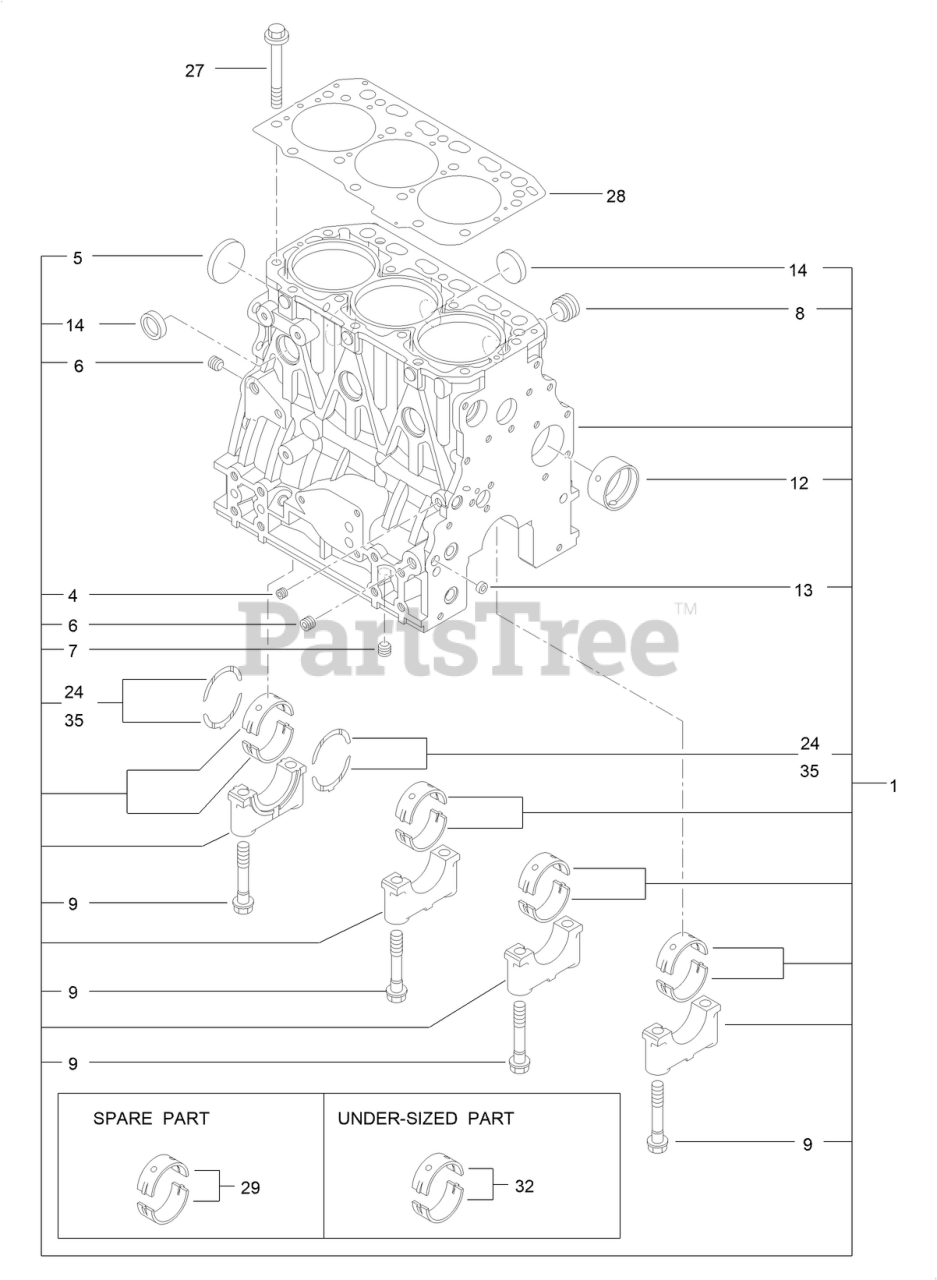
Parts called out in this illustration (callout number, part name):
1	CYLINDER BLOCK ASM
12	BUSHING
24	METAL-THRUST
28	HEAD GASKET ASM
29	METAL-MAIN
32	METAL-MAIN (0.25)
35	METAL-THRUST (0.25)
